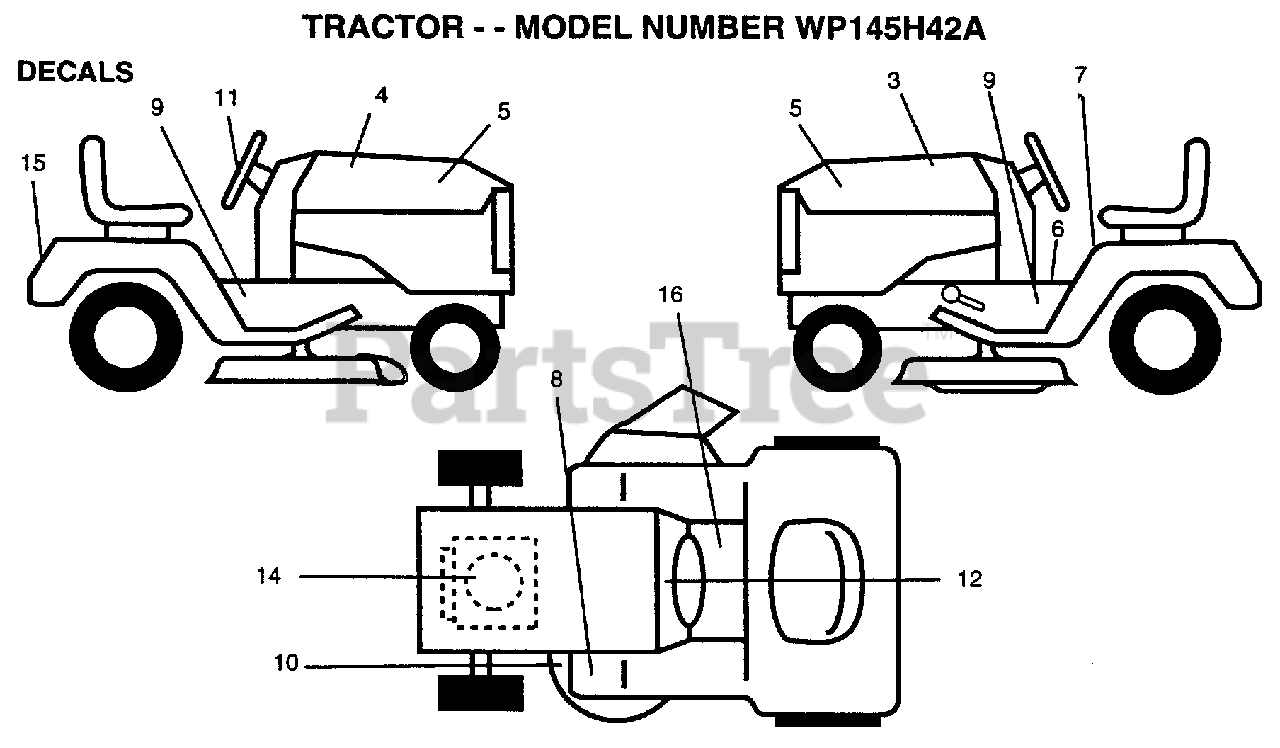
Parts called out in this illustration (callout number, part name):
3	DECAL.HOOD.LH
4	DECAL.HOOD.RH
5	DECAL.WP145H42A
6	DECAL BRAK PARK
7	DECAL
9	DECAL CHAS 42 HYD
10	DECAL
11	DECAL, INSERT
12	DECAL.DASH.INST.
14	DECAL, ENGINE
15	DECAL, FENDER LOGO
16	DECAL SADLE HYDRO
